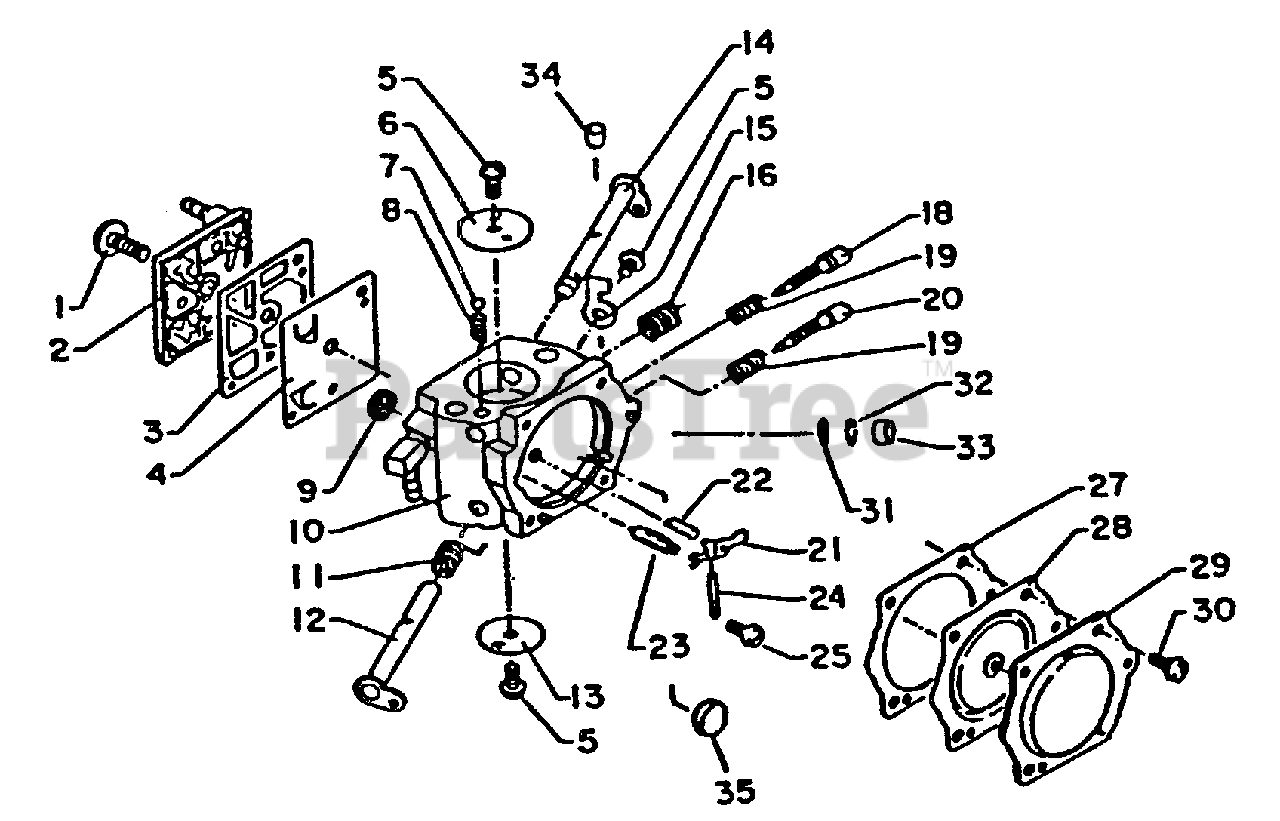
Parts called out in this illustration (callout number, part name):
1	SCREW, PUMP COVER
2	COVER, PUMP
3	REPAIR KIT
3	DIAPHRAGM/GASKET KIT
4	REPAIR KIT
4	DIAPHRAGM/GASKET KIT
6	VALVE, CHOKE
7	BALL, CHOKE
9	REPAIR KIT
10	BODY, CARBURETOR
11	SPRING, THROTTLE RETURN
12	SHAFT, THROTTLE
13	VALVE, THROTTLE
14	SHAFT, CHOKE
15	STOP, THROTTLE
16	SPRING, IDLE ADJUST
18	NEEDLE - LOW SPEED
19	REPAIR KIT
20	NEEDLE - HIGH SPEED
21	REPAIR KIT
22	REPAIR KIT
23	REPAIR KIT
24	REPAIR KIT
25	REPAIR KIT
27	REPAIR KIT
27	DIAPHRAGM/GASKET KIT
28	REPAIR KIT
28	DIAPHRAGM/GASKET KIT
29	COVER, METERING
30	REPAIR KIT
31	REPAIR KIT
32	REPAIR KIT
33	REPAIR KIT
35	REPAIR KIT
